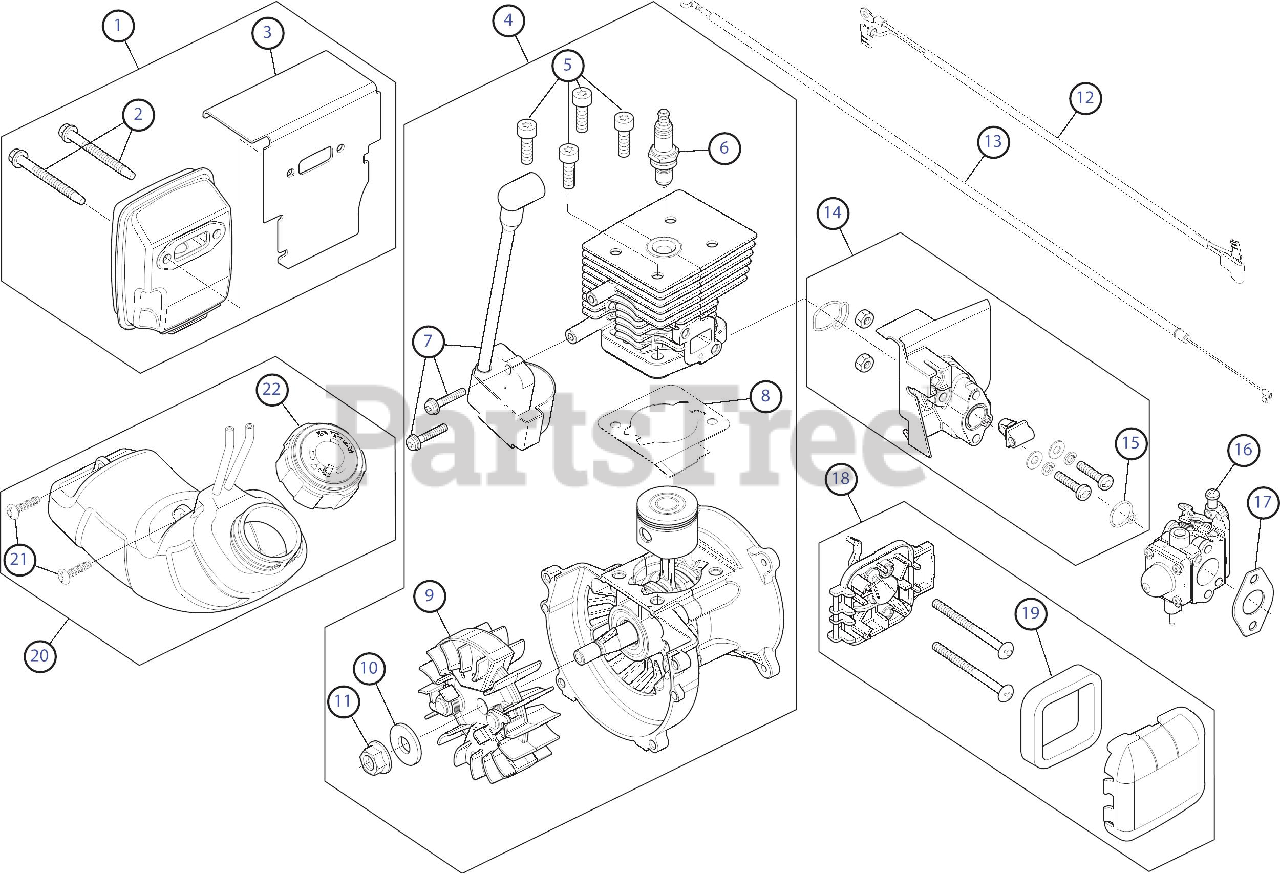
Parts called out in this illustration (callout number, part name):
1	Muffler Assembly (Incl. 2 & 3)
2	Muffler Screws
3	Muffler Gasket
4	Shortblock Assembly (Incl. 5 - 11)
6	Spark Plug
7	Module Assembly
8	Cylinder Gasket
9	Flywheel Assembly
13	Throttle Cable
14	Insulator Assembly (Incl. 15)
15	Insulator O-Ring
16	Carburetor Assembly (Incl. 17)
17	Carburetor Gasket
18	Air Cleaner Assembly (Incl. 19)
19	Air Filter
20	Fuel Tank Assembly (Incl. 21 & 22)
